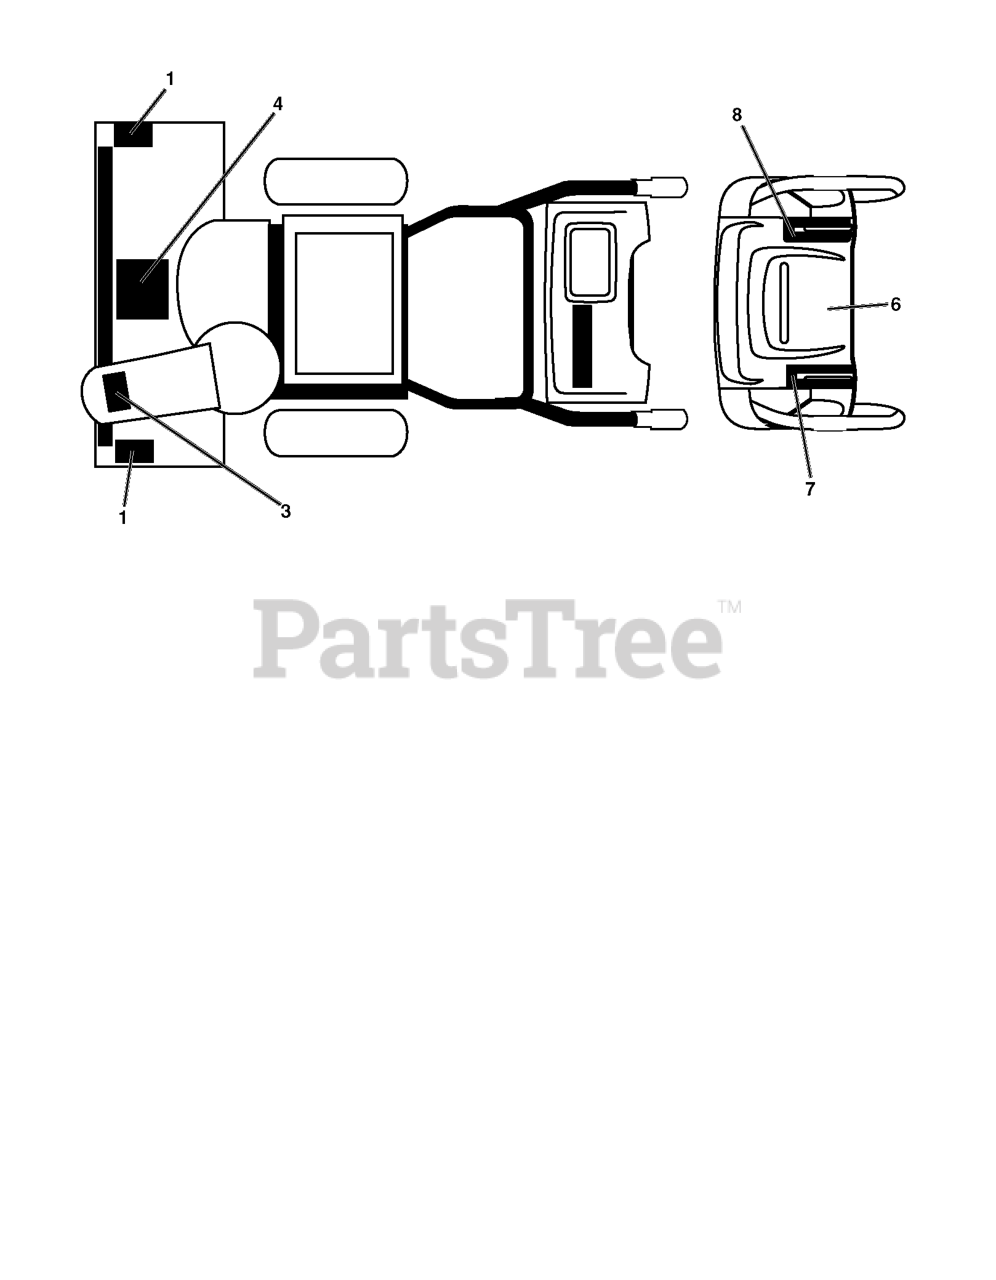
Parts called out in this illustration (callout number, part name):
1	DECAL.SNOWTHR.AUGER
3	DECAL.SNOWTHR.CHUTE.SAFETY
4	DECAL.SNOWTR.READ.OWN.MAN.E/F
6	DECAL, INSTRUCTION
7	DECAL.CONS.LT.WO/DEFL.GRY
8	DECAL.CONS.RT.SPD/LEV/PWRST.
